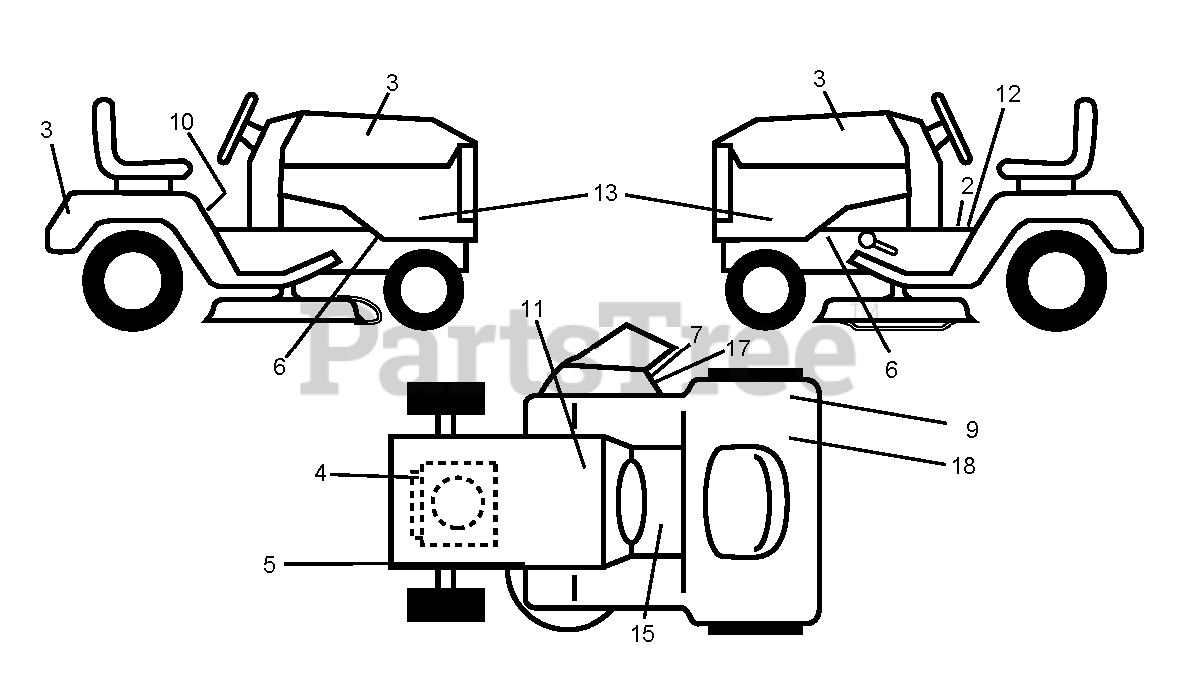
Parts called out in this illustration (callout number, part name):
2	DECAL PARK BRAKE
3	DECAL.HOOD.LOGO.ORANGE.HUSQVAR
4	DECAL
5	DECAL V BELT SCHEMATIC
7	DECAL.INTERNATIONL.CUTFINGER
9	DECAL
10	LABEL
11	DECAL BTRY SYMBOLS
12	DECAL
15	DECAL
17	DECAL, DEFLECT WARNING
18	DECAL 80 DBA
